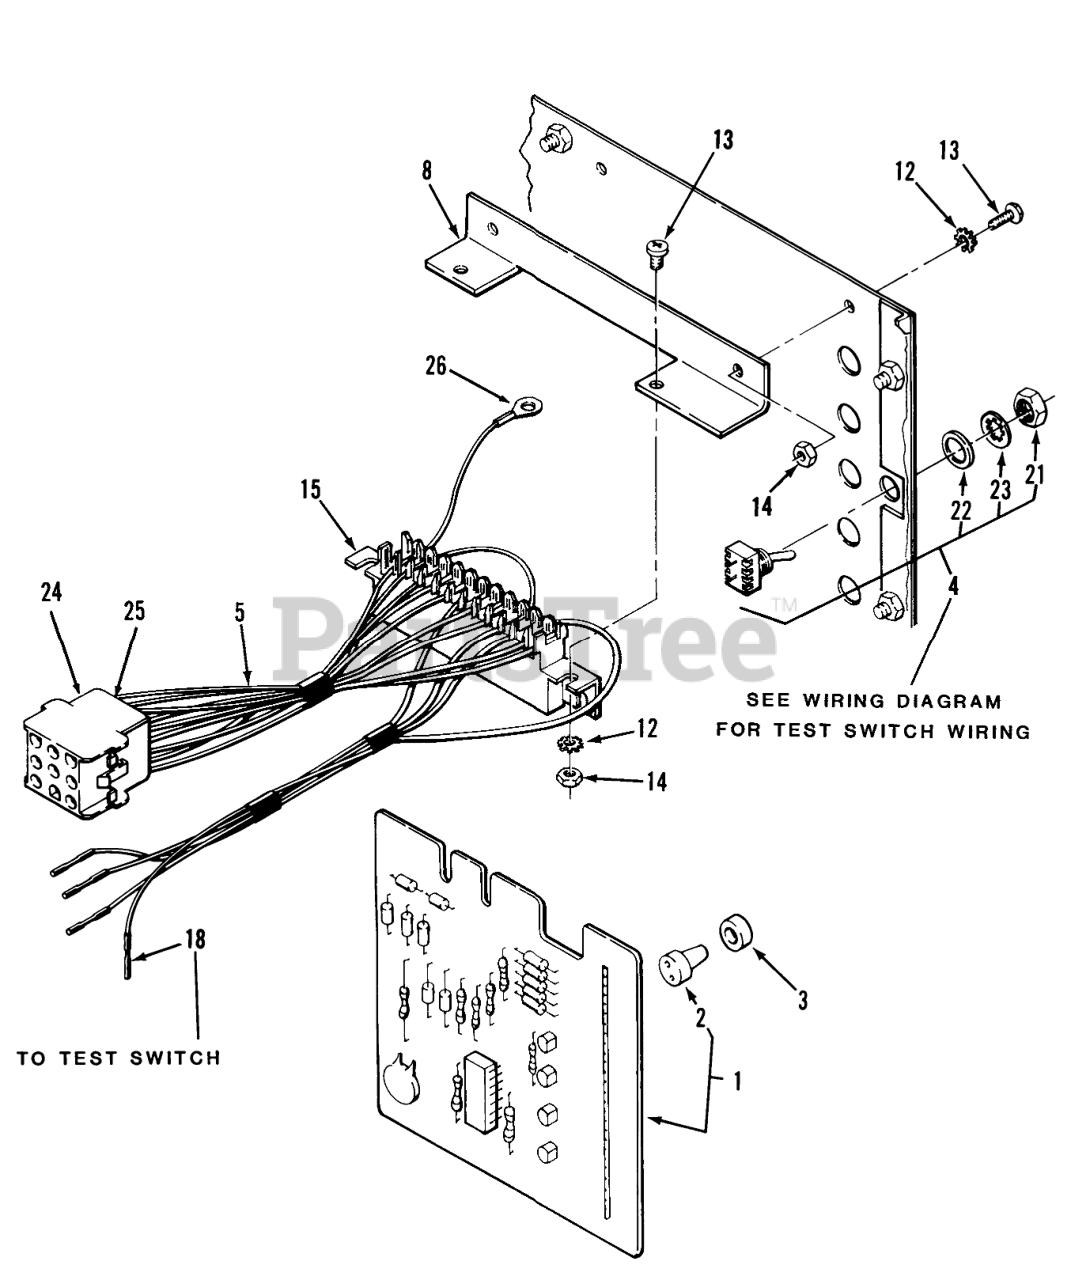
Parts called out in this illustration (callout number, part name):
1	P.C Board (Includes item 2)
2	LIGHT INDICATOR
3	ASSY LENS & BUSHING
4	SWITCH TOGGLE
5	P.C. BOARD HARNESS
8	BRACKET
12	Washer-Lock
13	SCREW
14	Nut
15	Molex Connector (Part of 6)
18	062 X 031 TAB RECEPT
21	NUT F/W 116796
22	RING LOCKING
23	Washer
24	9-CIRCUIT CAP
25	TERMINAL - SOCKET
26	No. 6 Ring Terminal
